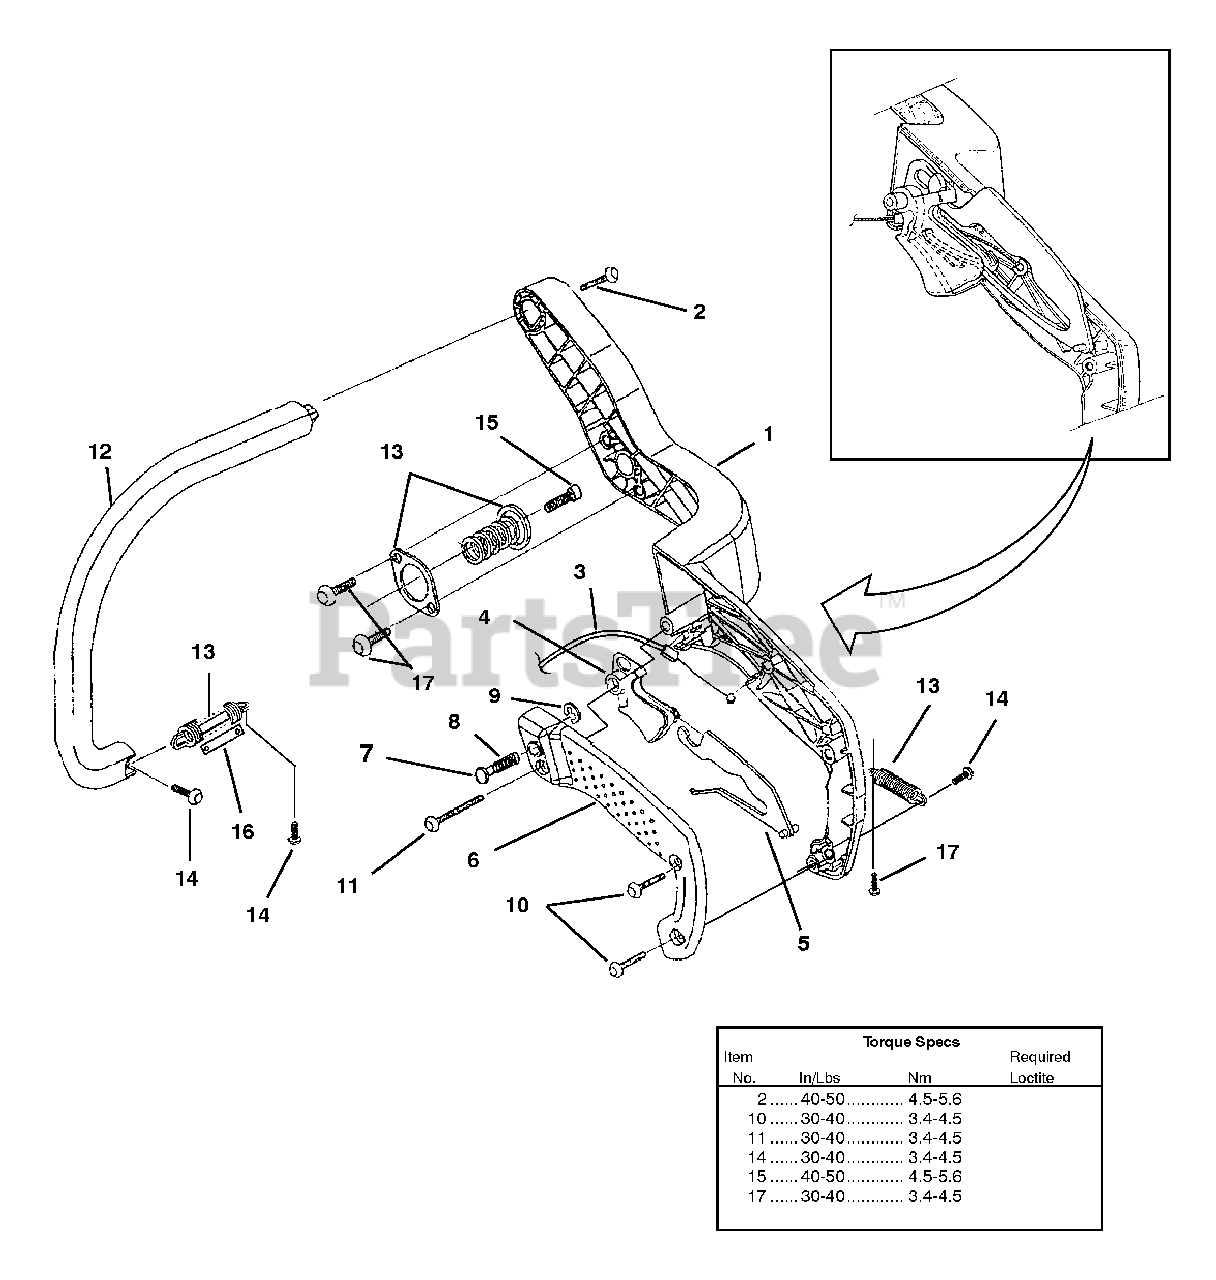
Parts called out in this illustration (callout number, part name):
1	Rear Handle Kit
2	Screw-Pan Hd. (12-14 x 1 1/2")
3	Throttle Cable
4	Trigger, Throttle
5	Throttle Lock Out
6	Handle Cover Kit
7	Throttle Lock Pin
8	Spring, Compression
9	Ring, Retainer
10	Screw, Thread Form (10-14 x 3/4")
11	Screw, Thread Form (10-14 x 1 3/8")
12	Front Handle Kit
13	Isolator Kit
14	Screw, Truss Hd. (10-14 x 5/8")
15	Screw, Truss Hd. (10-24 x 5/8")
16	Limiter, Isolator
17	Screw, Thread Form (10-14 x 1/2")
